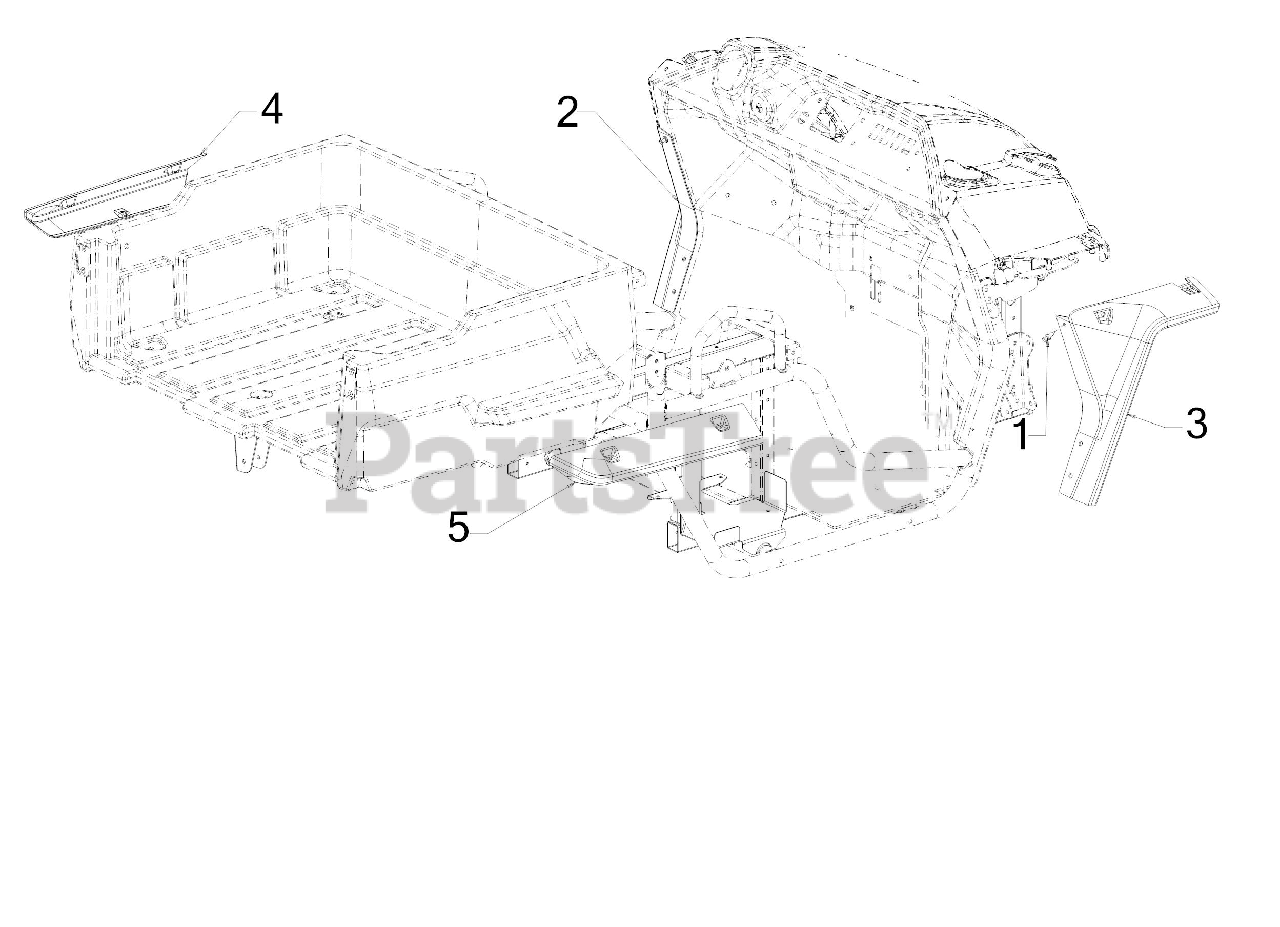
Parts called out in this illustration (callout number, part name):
1	PLASTIC RIVET
2	FRONT FENDER (LH) (YELLOW)
3	FRONT FENDER (RH) (YELLOW)
4	REAR FENDER (LH) (YELLOW)
5	REAR FENDER (RH) (YELLOW)
